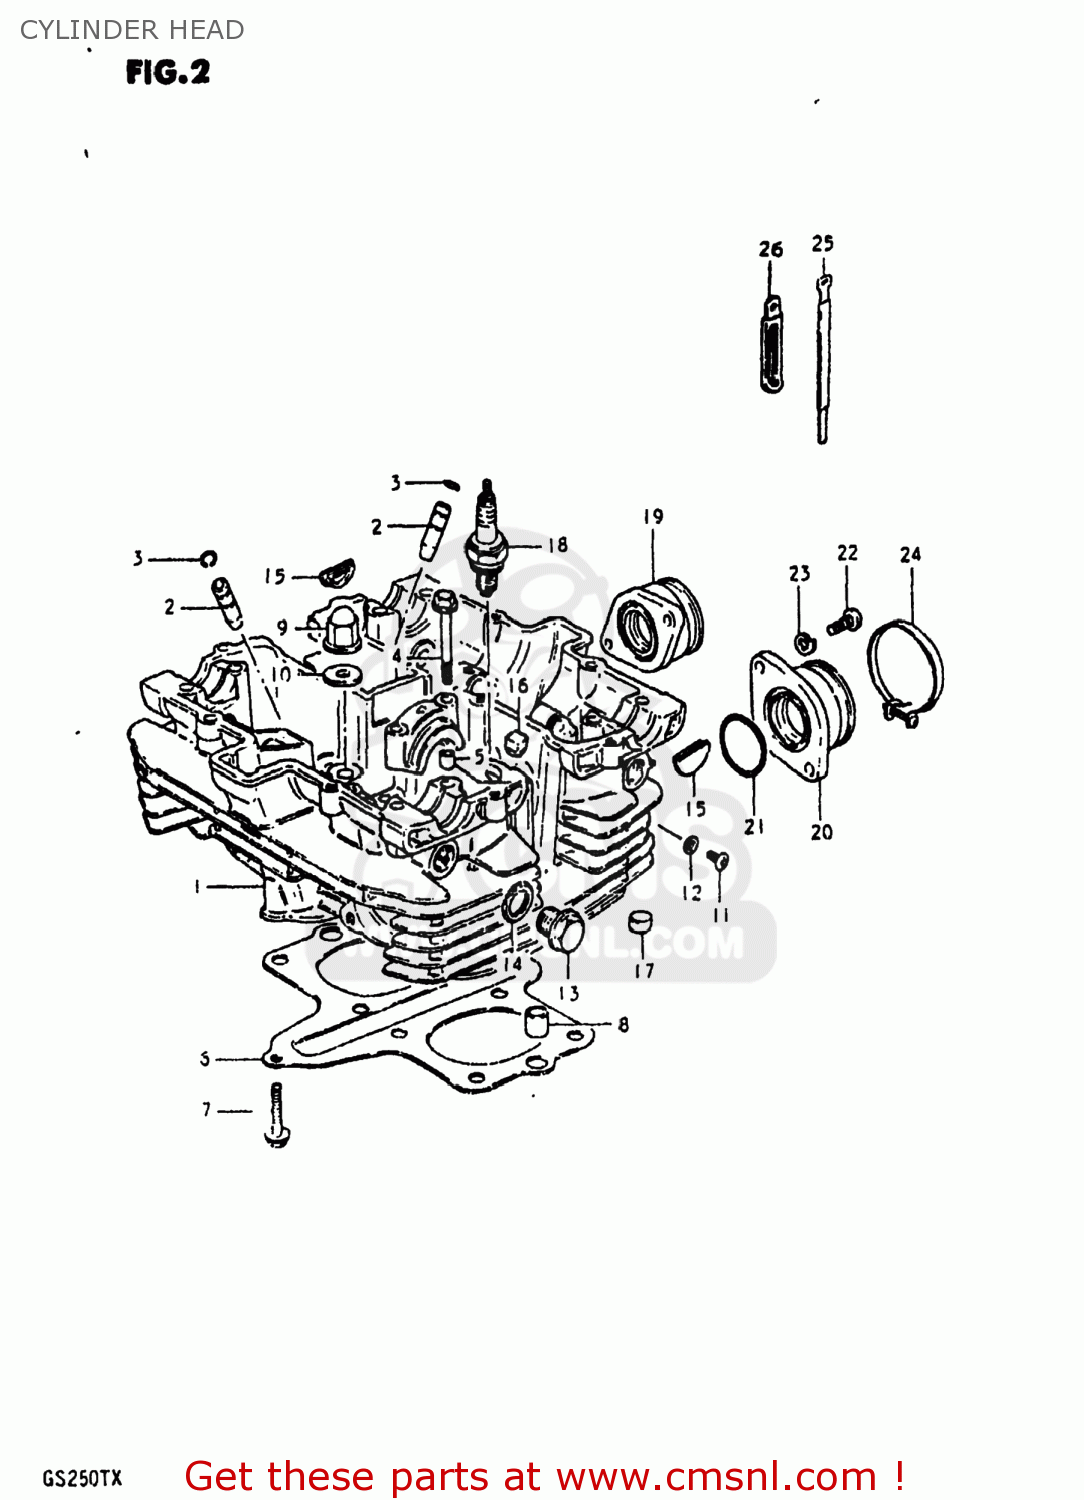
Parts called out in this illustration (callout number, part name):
1	HEAD ASSEMBLY,CYLINDER
2	GUIDE,INTAKE VALVE
3	RING,SNAP
4	BOLT(6X39)
5	PIN(6.2X8X11)
6	GASKET,CYLINDER HEAD (MCA)
7	BOLT
8	PIN
9	NUT
10	GASKET (NAS)
11	SCREW
12	GASKET(5.3X9.3X1.2) (NAS)
13	PLUG (14X12)
14	GASKET(14X19.2X2) (NAS)
15	PLUG
16	PAD,CYLINDER HEAD
17	PAD
18	SPARK PLUG D9EA
19	PIPE,INTAKE,R
20	PIPE,INTAKE,L
21	O-RING (D:2.4 ID:29.7)
22	SCREW
23	LOCK WASHER
24	CLAMP
25	CLAMP
26	CLAMP
